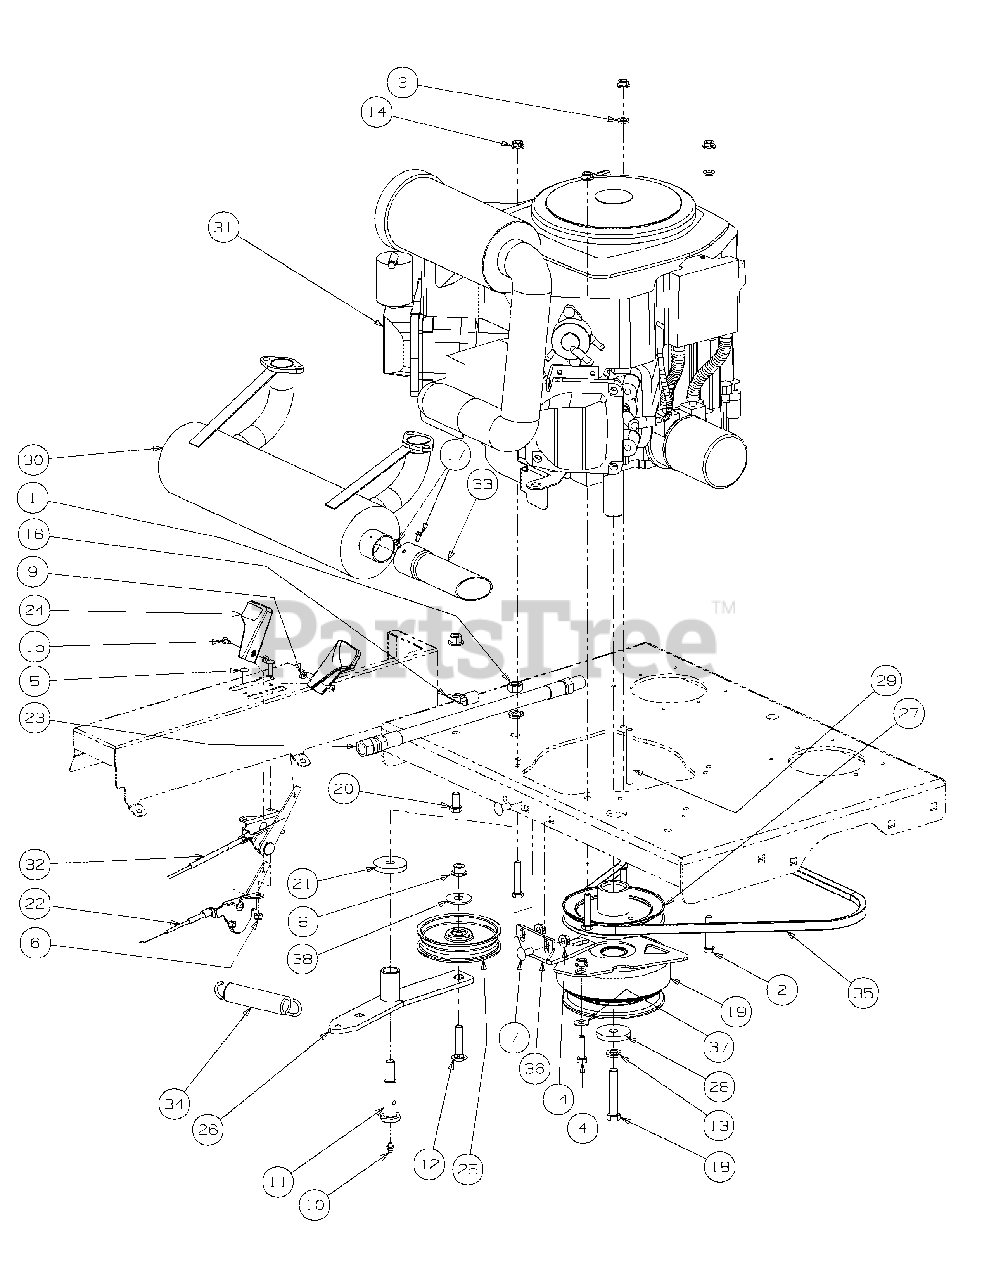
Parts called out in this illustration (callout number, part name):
1	Hex Nut, 7/16-14
2	HHCS, 5/16-18, 1-3/4
3	Flat Washer, 5/16
4	HHCS, 5/16-18 x 1-1/4
5	Round Hd. Machine Screw, 10-32 x 3/4
6	Lock Nut, Nylon Insert, 10-32
7	Carriage Bolt, 5/16-18 x .75
8	Flange Lock, Hex Nut, 3/8-16
9	Nut Washer, W/Star, 8-32
10	Grease Fitting, 1/4-28 x 3/16
11	Shoulder Screw, 7/16-14
12	Hex Carriage Screw, 3/8-16, 1.75
13	Lock Washer, 7/16
14	Hexflange Lock Nut, 5/16-18
15	Machine Screw, 8-32, .375
16	Clip, Heat Shield Cable
17	Screw, #8-32 x 0.375
18	Capscrew, 7/16-20 x 2.50
19	Clutch Brake, 1.125 ID
20	Hex Cap Screw, 3/8-16, .750
21	Flat Washer, 7/16 ID x 1.75 OD x .25
22	Throttle, Control Cable, 45.0
23	Oil Drain Hose
24	Control Throttle Knob
25	Flat Pulley with Flanges
26	Engine Idler Arm
27	Pump Drive Pulley
28	Flat Washer, 7/16 ID x 1.75 OD x .25
29	Key, 1/4 x 1/4 x 3
30	Muffler Accessory Kohler
31	Engine, 27HP Kohler (CV-740-0015)
31	Engine, 27HP Kohler (CV-740-0039)
32	Choke Control Cable, 38.0
33	Muffler Accessory Exhaust Tube
34	Extension Spring, .98 OD x 5.00
35	Belt, 50.0 Lg
36	Retainer Clutch Assembly, Ogura
37	Flat Washer, 5/16
38	Flat Washer, .406 ID, 1.0 OD, .105
